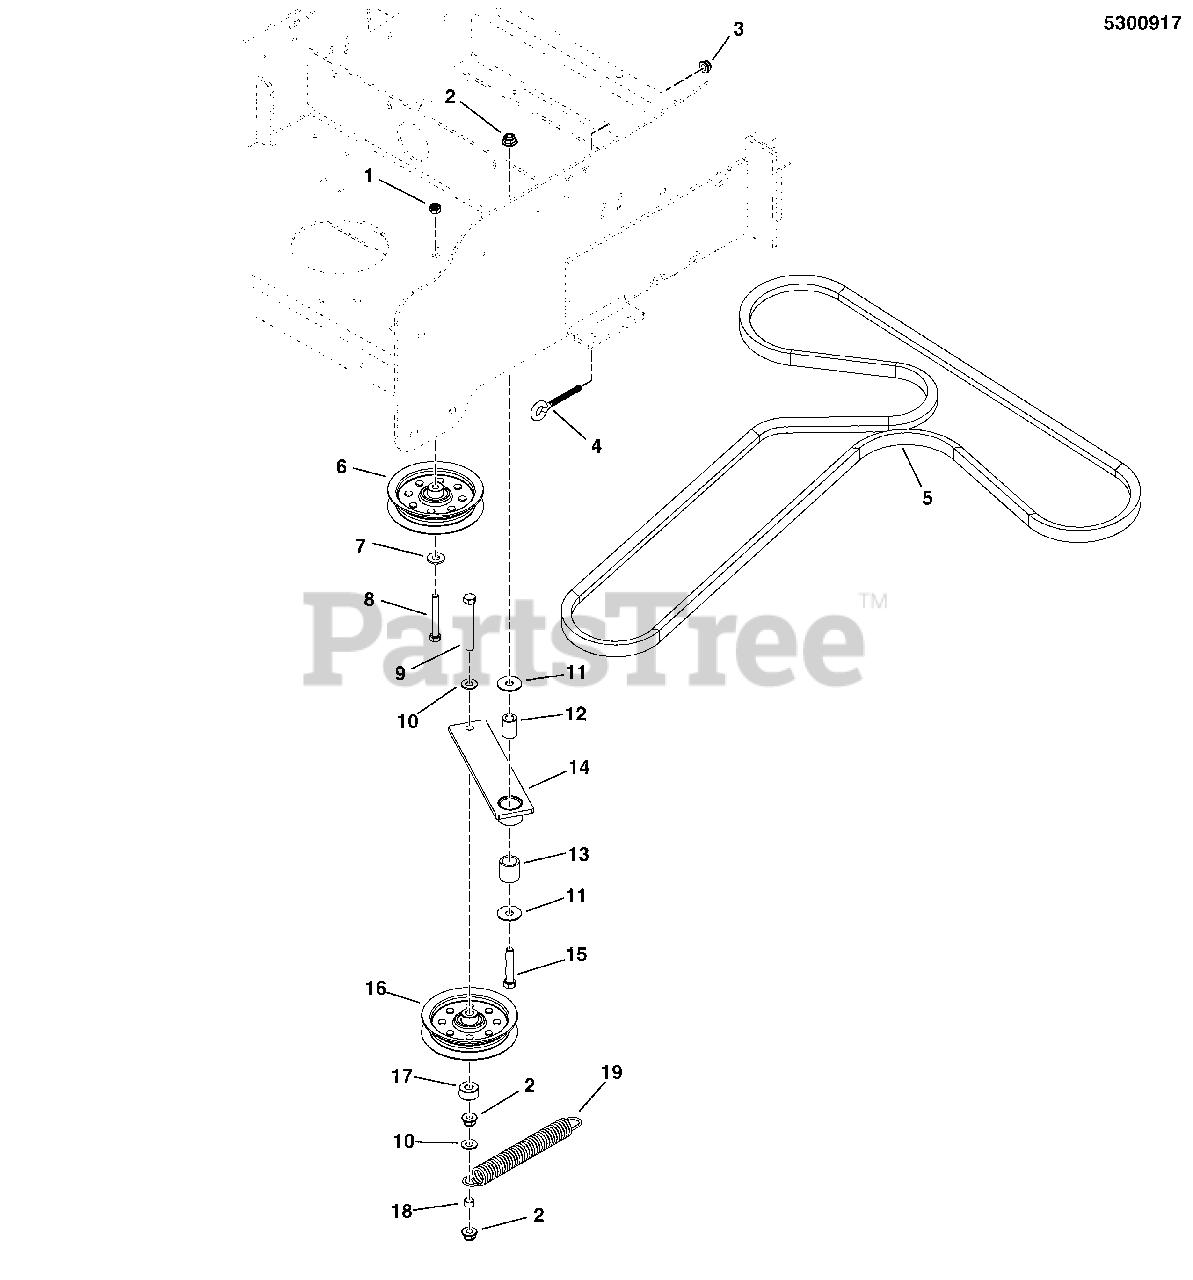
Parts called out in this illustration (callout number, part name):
1	NUT, Hex Lock, 5/16-18
2	NUT, 3/8-16, Hex Flange Nylock
3	NUT, Ny Lock Flange, 5/16-18
4	EYE BOLT, 5/16-18 X 3-1/2, 2-1/8 THRD.
6	PULLEY, IDLER, STATIONARY
7	WASHER, 5/16 USS
8	CAPSCREW, Hex Head, 5/16-18 x 2-1/2
9	BOLT, 3/8-16 X 3 GD5 TFL
10	WASHER, Flat, 3/8
11	WASHER, Fender, 3/8
12	SPACER, .39 X .75 X 1.06
13	BUSHING, BRASS, 3/4 X 1 X 1
14	WELD, IDLER ARM, SNAPPER PRO - BLK
15	CAPSCREW, Hex Head, 3/8-16 x 2
16	PULLEY, IDLER, ADJUSTABLE
17	SPACER, .39 X 1.00 X .50, PM, CZ
18	SPACER, .38 X .50 X .27, CZ
19	SPRING, Extension
20	BOLT, HEX FLG, SER GD5 3/8-16X2, PATCH, CZ
